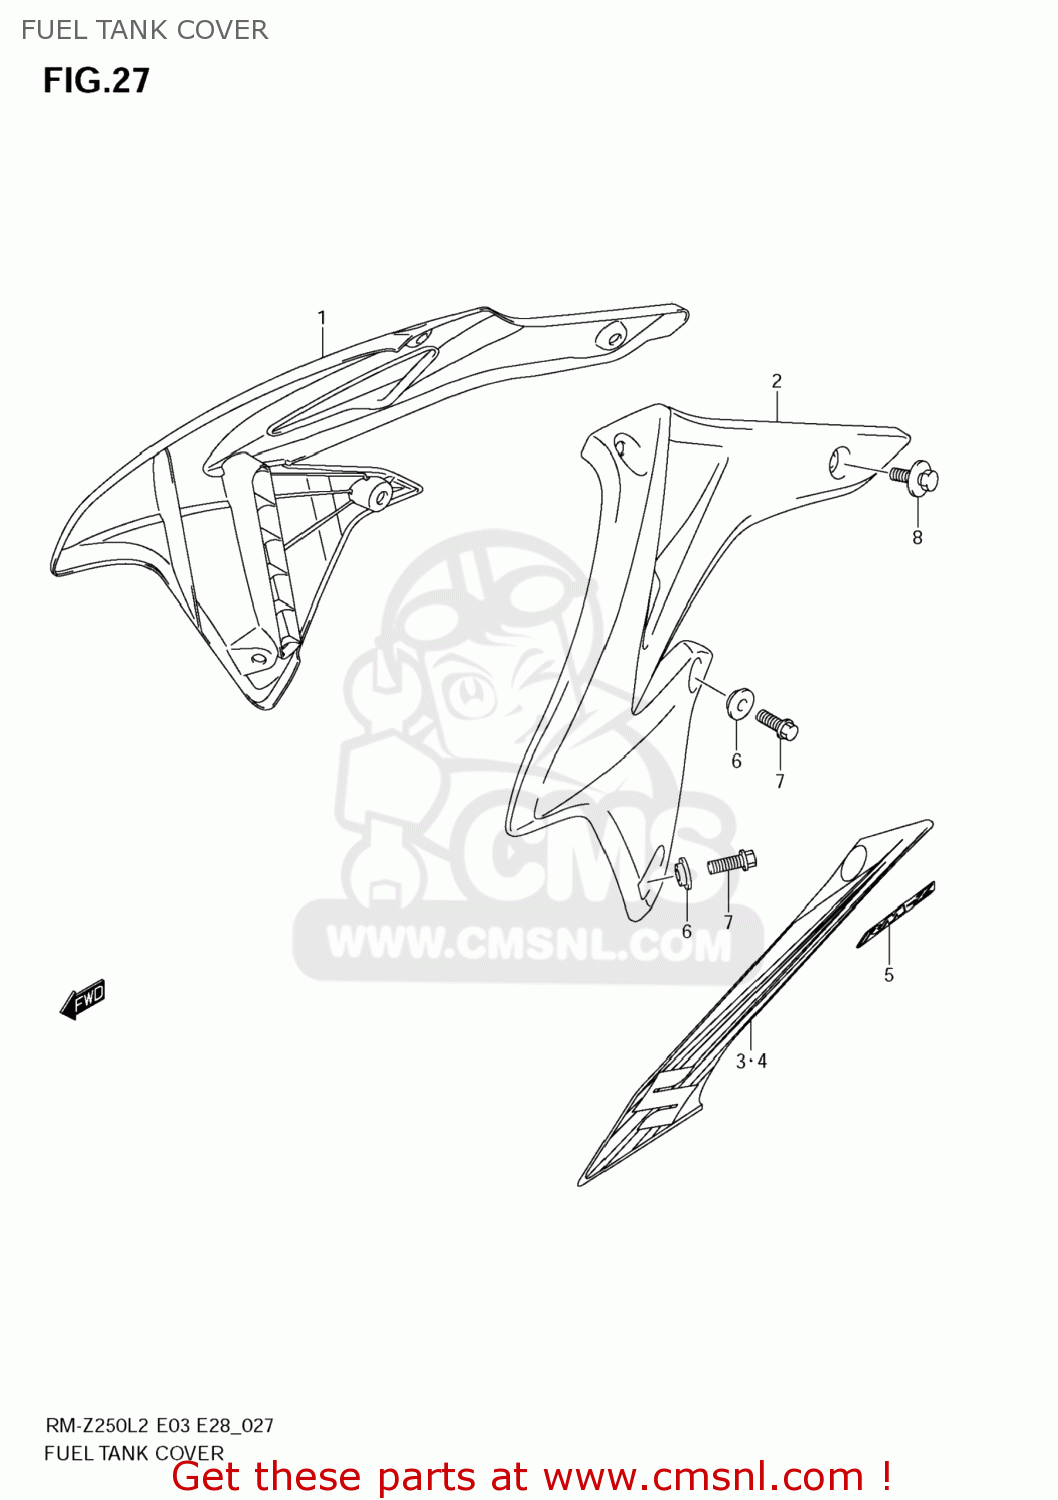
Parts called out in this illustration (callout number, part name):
1	COVER,FUEL TANK,R
2	COVER,FUEL TANK,L
3	TAPE,FUEL TANK COVER,R
4	TAPE,FUEL TANK COVER,L
5	EMBLEM,RADIATOR COVER
6	WASHER,FR FENDER
7	BOLT
8	BOLT(6X12)
